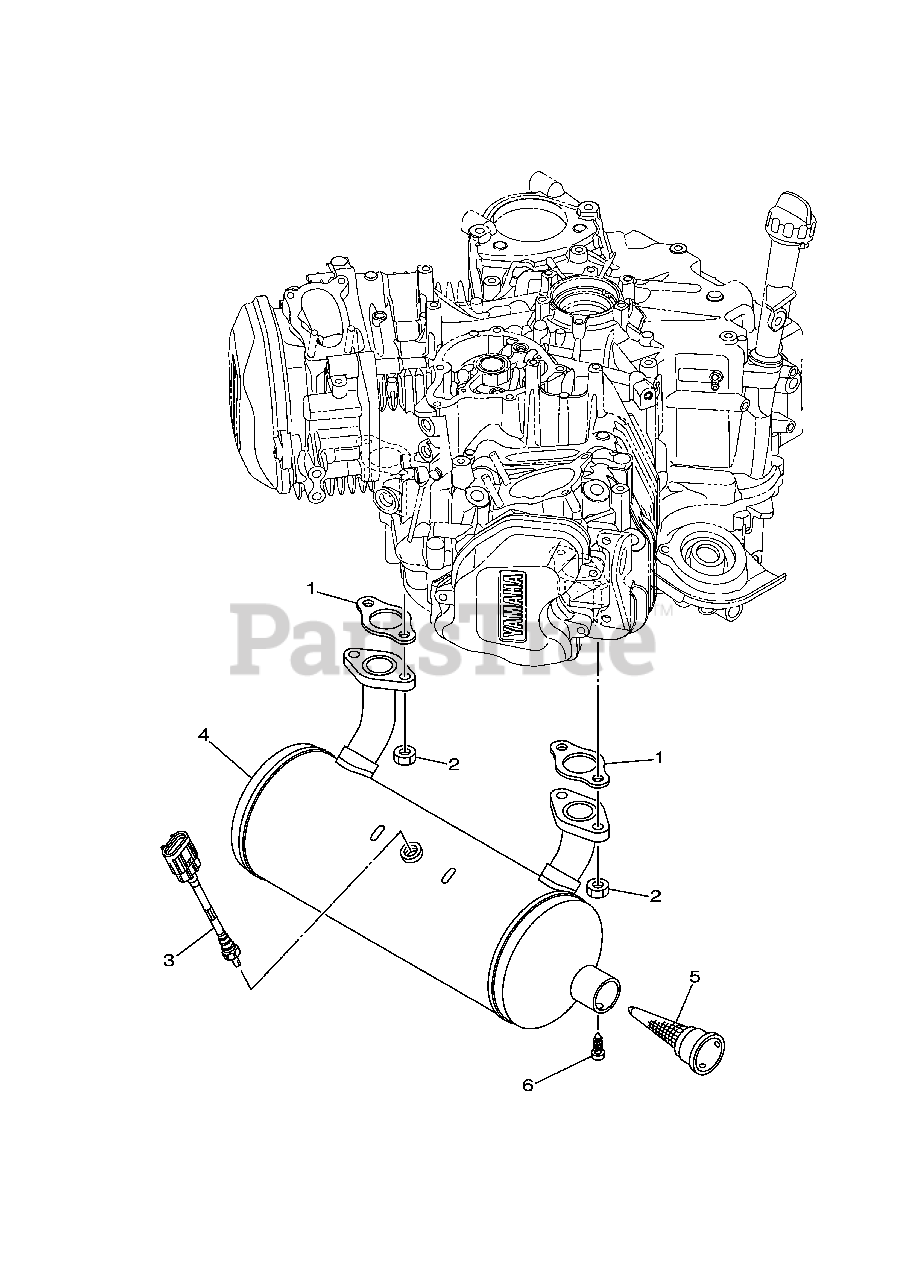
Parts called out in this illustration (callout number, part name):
1	GASKET, MUFFLER YAMAHA 824
2	NUT, HEXAGON
3	SENSOR, OXYGEN
4	MUFFLER 1
5	ARRESTER, SPARK
6	SCREW, TAPPING
